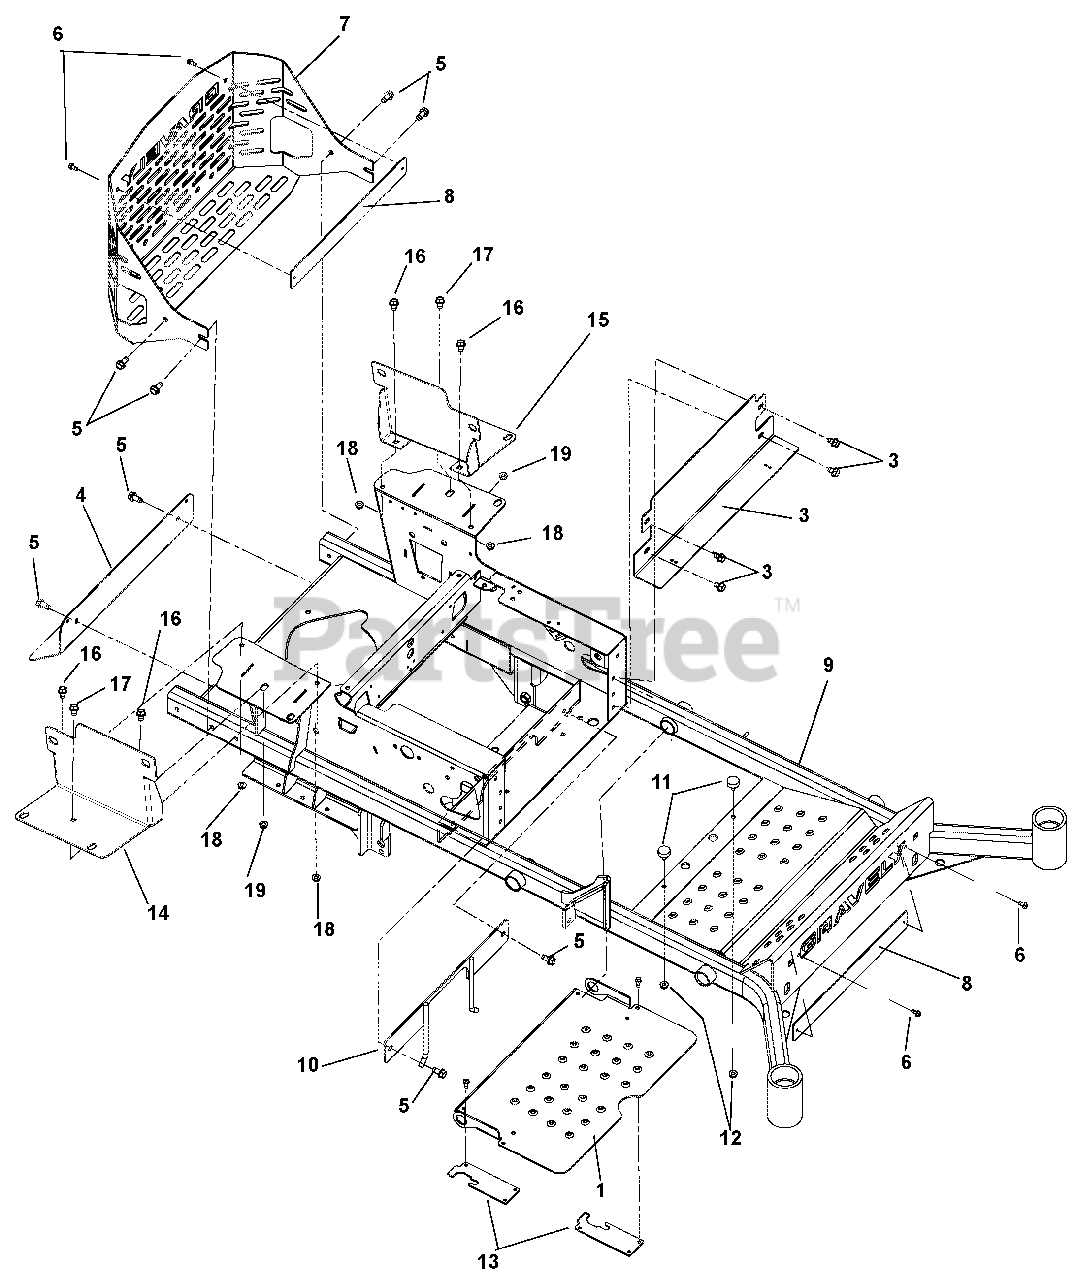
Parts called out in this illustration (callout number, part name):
1	Foot Plate
2	Kick Plate
3	Screw, Tapping .38-16 x .50 Hex Washer Head Thread Rolling
4	Muffler Heat Shield
5	Screw, Tapping .38-16 x .75 Hex Washer Head
6	Screw, Tapping .25-20 x .50 Hex Washer Head
7	Pro-Turn 100 Bumper
8	Bumper Plate
9	Frame, Pro-Turn 100 100 48"
10	PTO Belt Finger Weldment
11	Bumper, Rubber
12	Nut, Spin Lock Flange .312-18
13	Pro-Turn 100CE Foot Plate Finger Cover
14	Bracket, Tank Mount Right Hand
15	Bracket, Tank Mount Left Hand
16	Bolt, Round Head Square Neck .38-16 x 1.00 Grade 5
17	Bolt, Round Head Square Neck .31-18 x .75 Grade 5
18	Nut, Nyloc Flange .38-16
19	Nut, Nyloc Flange .31-18
